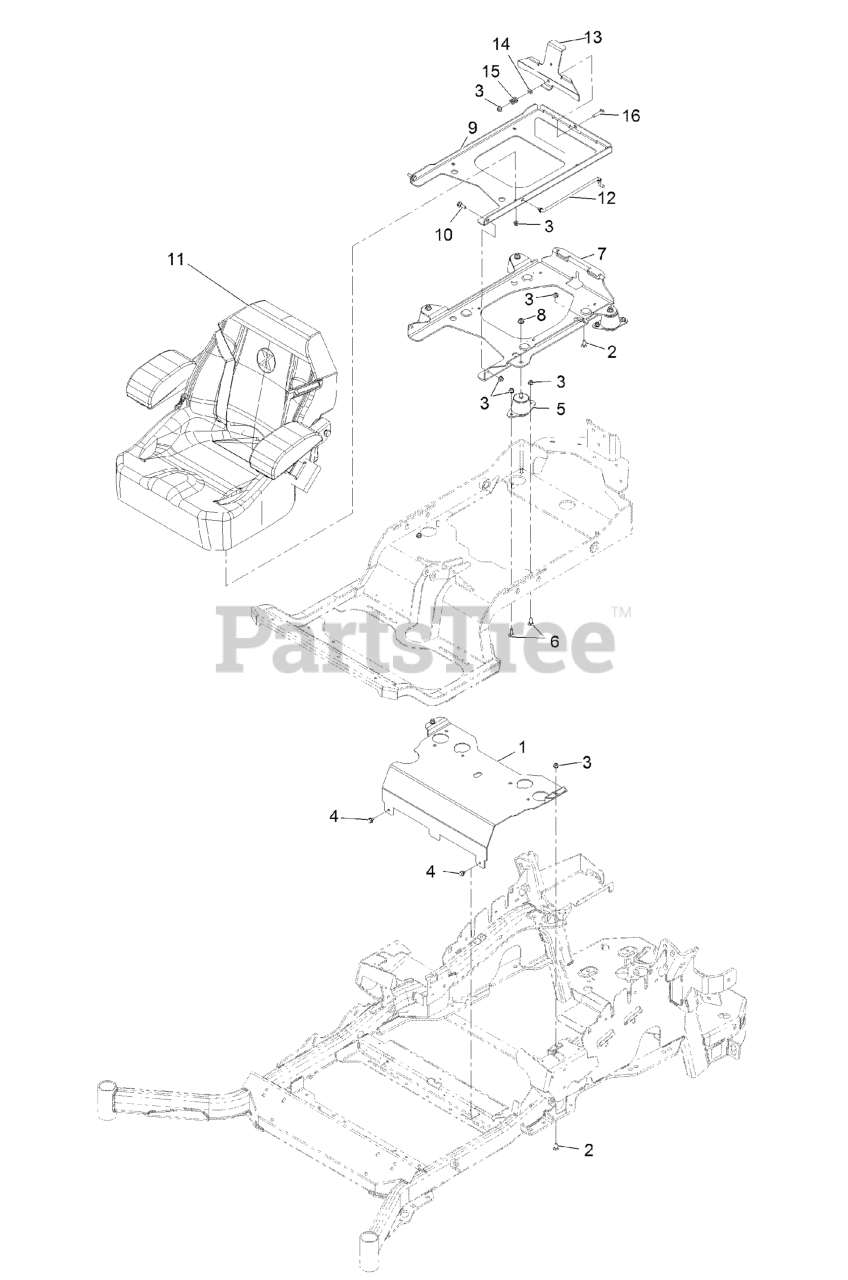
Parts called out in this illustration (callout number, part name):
1	PLATE-MOUNT, SHOCK
2	MOUNT-LOWER
3	BRACKET-BEARING
4	HOUSING-BEARING, FLANGE
5	BEARING
6	ARM-TRAILING
7	SUBFRAME ASM
7:2	DECAL-DANGER
7:3	DECAL-BRAKE, PARKING
7:4	BUSHING-FLANGE
8	BRACKET-MOUNTING
8:2	DECAL-ADJUSTMENT, RIDE
8:3	DECAL-LOCK, CAM
9	SCREW-CARR
11	SPACER-ALUMINUM
12	Nut-Lock 1/2-13
14	BOLT-SHOULDER
15	SHOCK/SPRING ASM
16	CAM LOCK ASM
16:2	CAP-LOCK
16:4	NUT-HEX
17	PLATE-STOP
18	KNOB-FRONT
22	SHOCK/SPRING ASM
24	ISOLATOR-SEAT
25	BOLT-CARR
26	NUT-HF, NI
27	PLATE-SUPPORT, ISO SEAT
28	NUT-HF, NI
29	PLATE-FRAME, SEAT
30	SCREW-SHOULDER
31	SEAT-EXMARK STANDARD
32	ROD-PROP
33	LH PLATE ASM (W/STUDS)
34	SCREW-CARR
35	SCREW-HH
36	BEARING-NEEDLE
37	BUMPER-RUBBER
39	SCREW-CARR
40	PLATE-LATCH,SEAT
41	WASHER-PLAIN
42	SPRING-COMPRESSION
43	BOLT-CARR
51	SCREW-HH
57	WASHER-FLAT
58	SCREW-HH, THREAD LOCKING
60	WASHER-THRUST
61	COVER-HOSE
62	TIE-CABLE
65	COVER-SHOCK
66	DECAL-SERVICE AID
67	WASHER-FLAT
71	RH PLATE ASM (W/STUDS)
72	Bolt-Carriage 5/16-18 X 1 1/4
